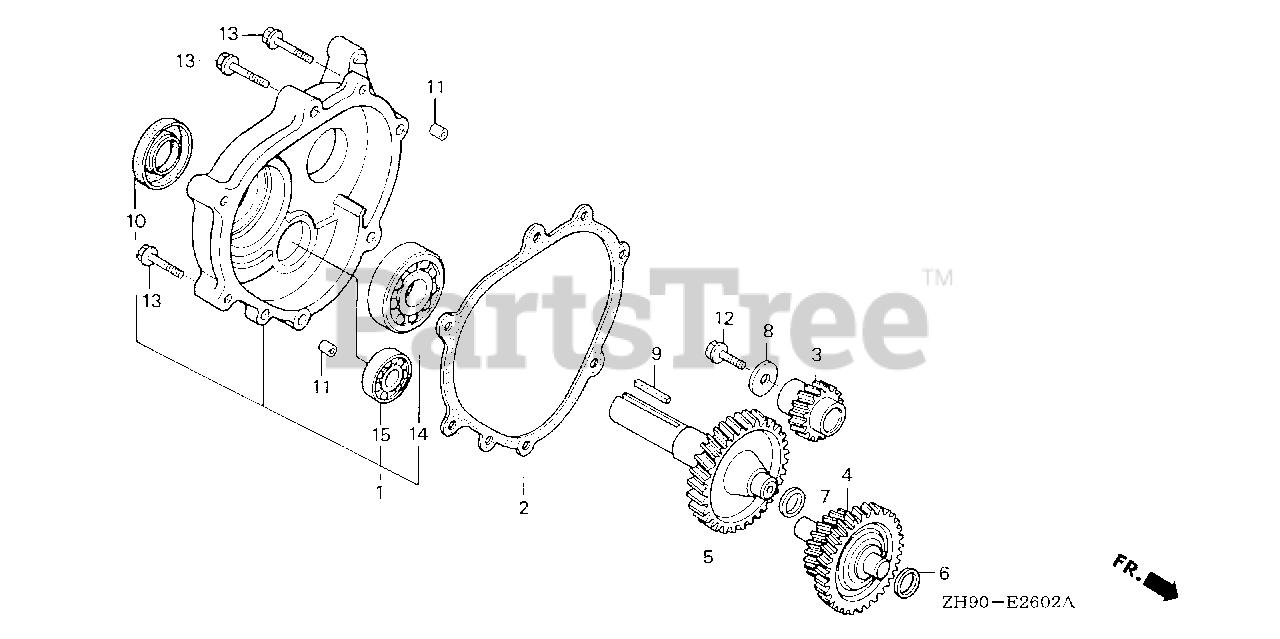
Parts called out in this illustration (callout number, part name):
1	COVER ASSY., REDUCTION CASE
2	GASKET, CHAIN CASE COVER
3	GEAR, PRIMARY DRIVE (17T)
4	COUNTERSHAFT
5	SHAFT, P.T.O. (H-TYPE)
6	SHIM A
7	SHIM B
8	WASHER (8MM)
9	KEY (6.3X6.3X43)
10	OIL SEAL (30X46X8)
11	PIN A, DOWEL (8X14)
12	BOLT, FLANGE (8X25)
13	BOLT, FLANGE (8X40) Use up to Engine SN 1003236.
14	BEARING, RADIAL BALL (6206)
15	BEARING, RADIAL BALL (6302)
